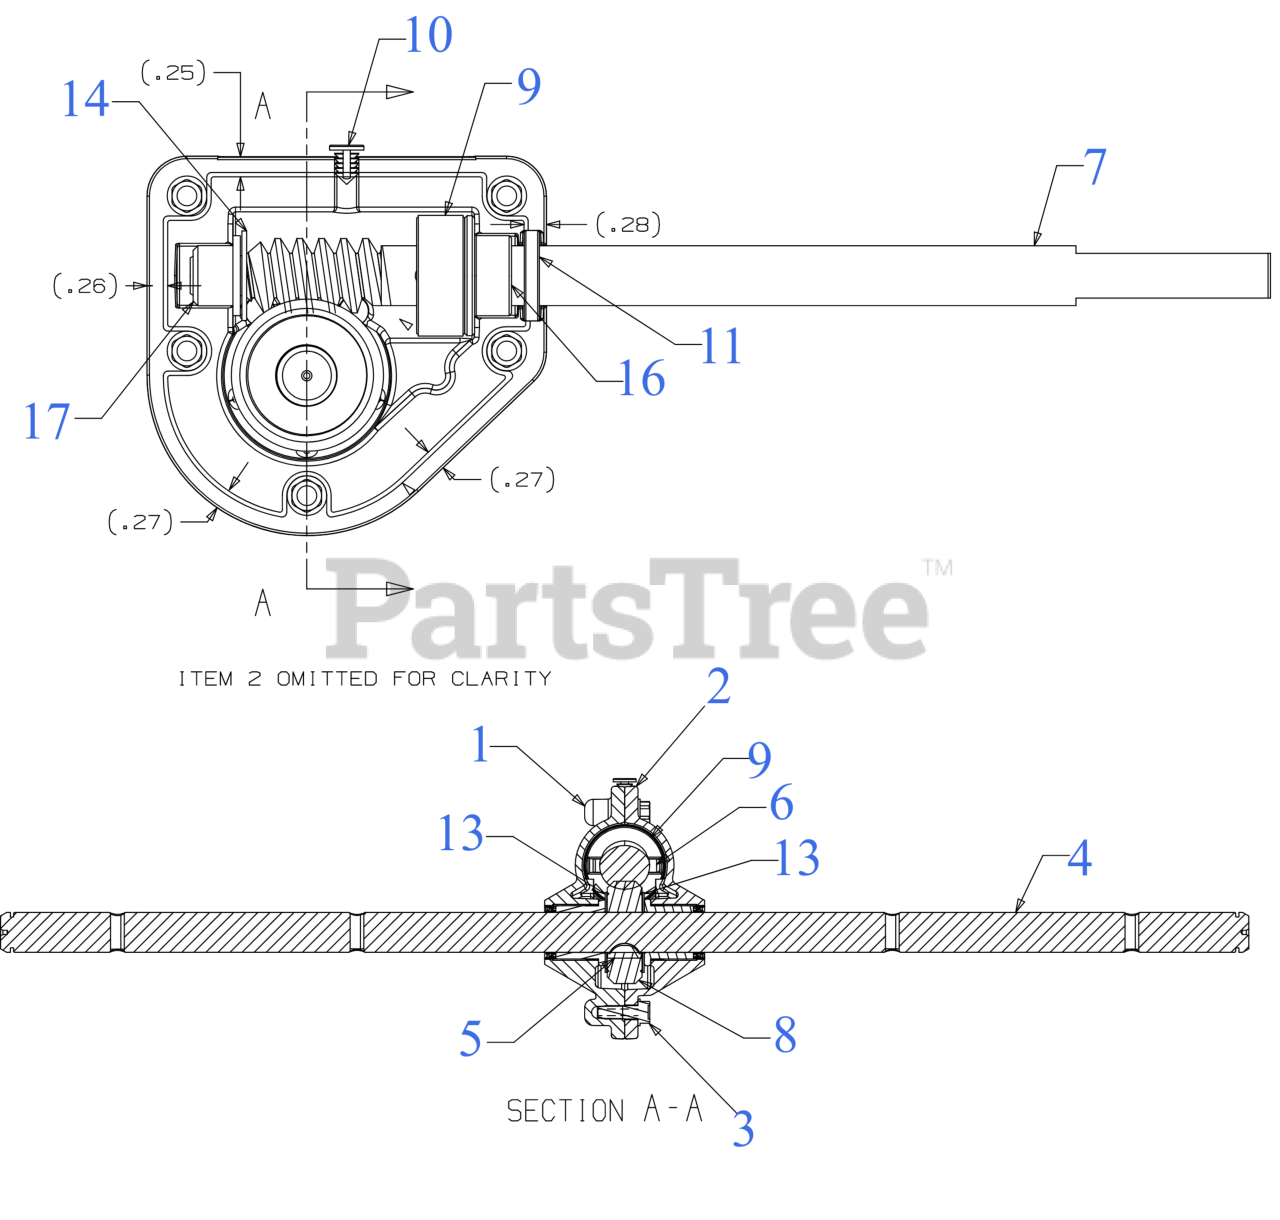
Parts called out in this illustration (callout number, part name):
1	REDUCER HOUSING ASSEMBLY (RH)
2	REDUCER HOUSING ASSEMBLY (LH)
3	SCREW 1/4-20 x .750
4	24" AUGER SHAFT
5	KEY 3/16 x 5/8 HI-PRO
7	WORM SHAFT
8	WORM GEAR 20T
9	COLLAR-THRUST .756ID x .600
11	OIL SEAL .75 x 1.131 x .188
13	THRUST WASHER
14	FLAT WASHER
15	ALVANIA GREASE
16	FLANGE BEARING
17	FLANGE BEARING
